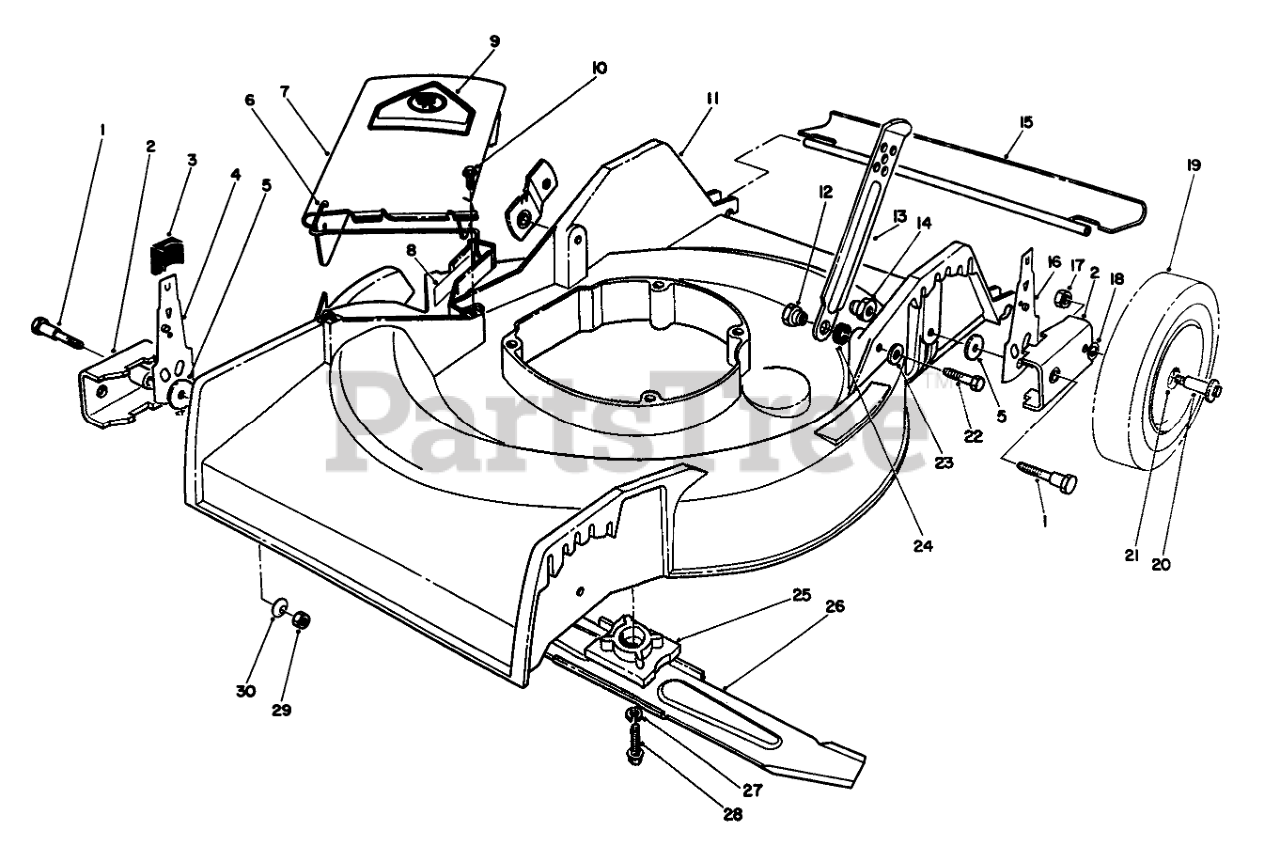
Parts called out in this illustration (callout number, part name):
1	PIVOT SCREW
2	HP PIVOT ARM ASM
3	KNOB-ARM
4	SPRING ARM ASSEMBLY
5	PIVOT WASHER
6	SPRING HINGE
7	Deflector (Incl. Ref. #6 & 9)
8	DANGER DECAL
9	DECAL-DANGER
10	SCREW-HWH
11	Housing Assembly (Incl. Ref. #8)
12	HANDLE PIVOT NUT
13	HANDLE LATCH
14	HANDLE PIVOT NUT
15	SHIELD - TRAILING
16	SPRING ARM ASSEMBLY
17	Nut
18	WASHER
19	Wheel & Tire Assembly (Incl. Ref. #21)
20	BOLT-WHEEL
21	BUSHING
22	SCREW-HH
23	WASHER-LOCK
24	SPACER
25	BLADE RETAINER
26	Blade
27	WASHER-LOCK
28	SCREW-HH
29	NUT-LOCK, NI
30	WASHER-BELLEVILLE
